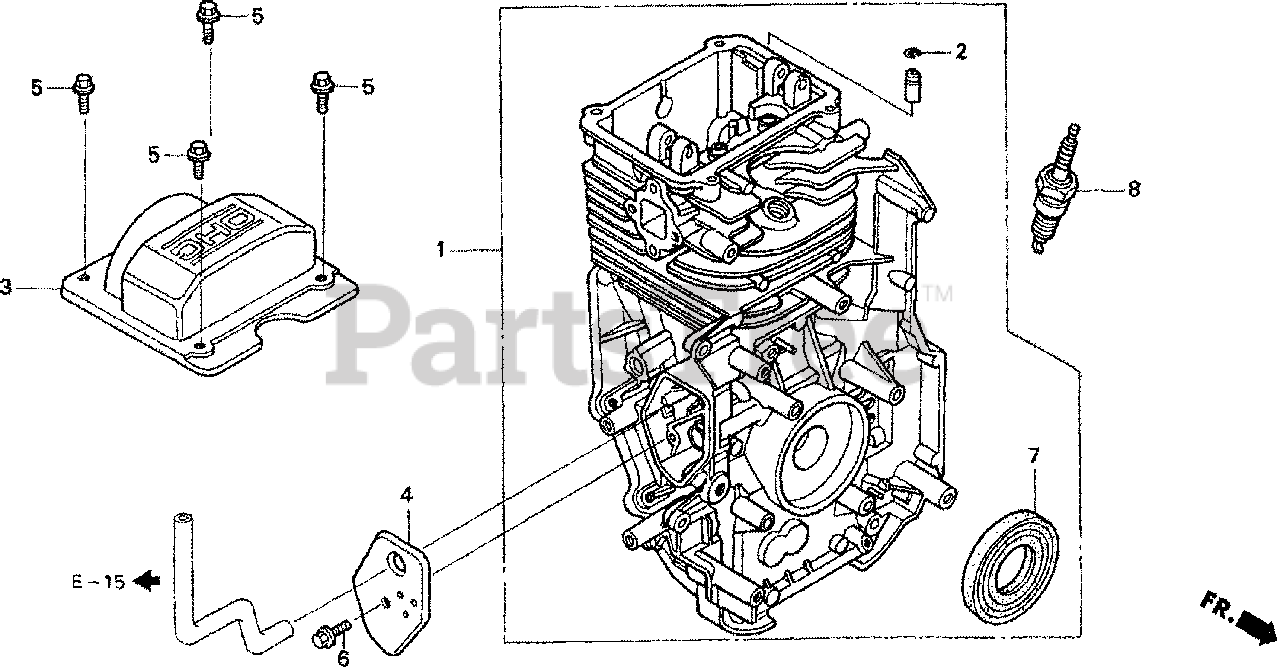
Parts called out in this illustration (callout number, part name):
1	CYLINDER ASSY. (010)
2	CLIP, VALVE GUIDE
3	COVER, HEAD
4	COVER, BREATHER (BREATHER VALVE ASSY.)
5	BOLT, FLANGE (6X12) (CT200)
6	BOLT, FLANGE (6X14)
7	OIL SEAL (25.4X62X6)
8	SPARK PLUG (BPR6ES) (NGK)
